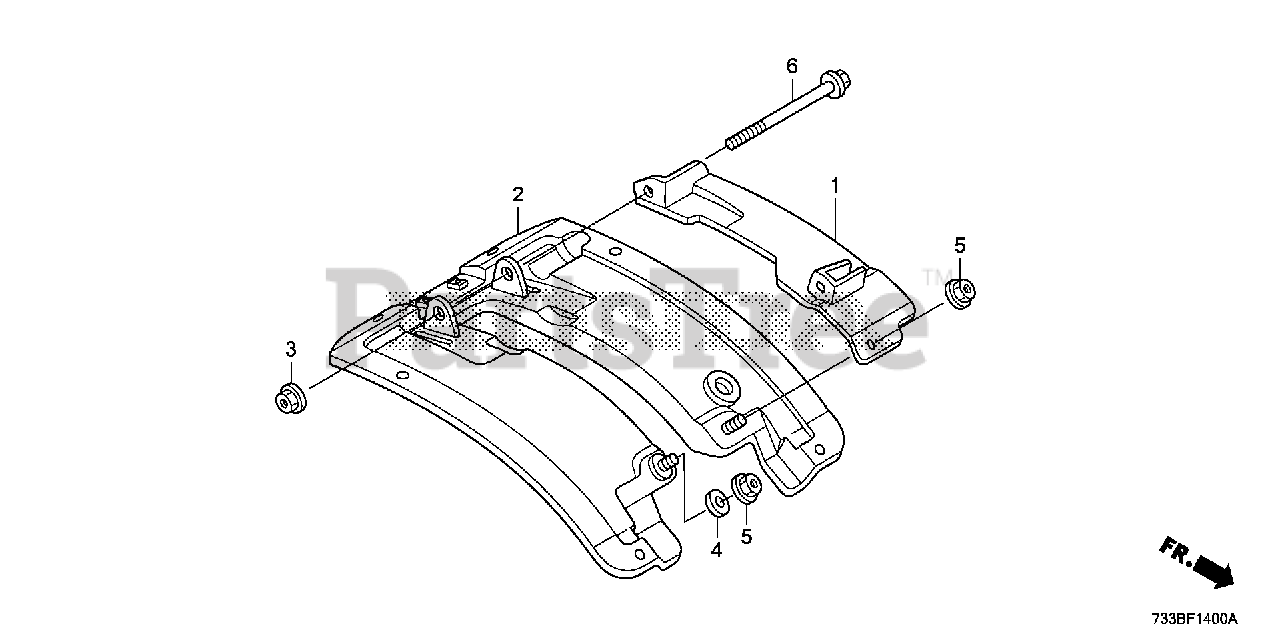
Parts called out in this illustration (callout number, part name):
1	PLATE, REINFORCE
2	FENDER, MAIN *R280* (POWER RED)
3	NUT, FLANGE (10MM)
4	WASHER (9X22X4.5)
5	NUT, FLANGE (8MM)
6	BOLT, FLANGE (10X90)
